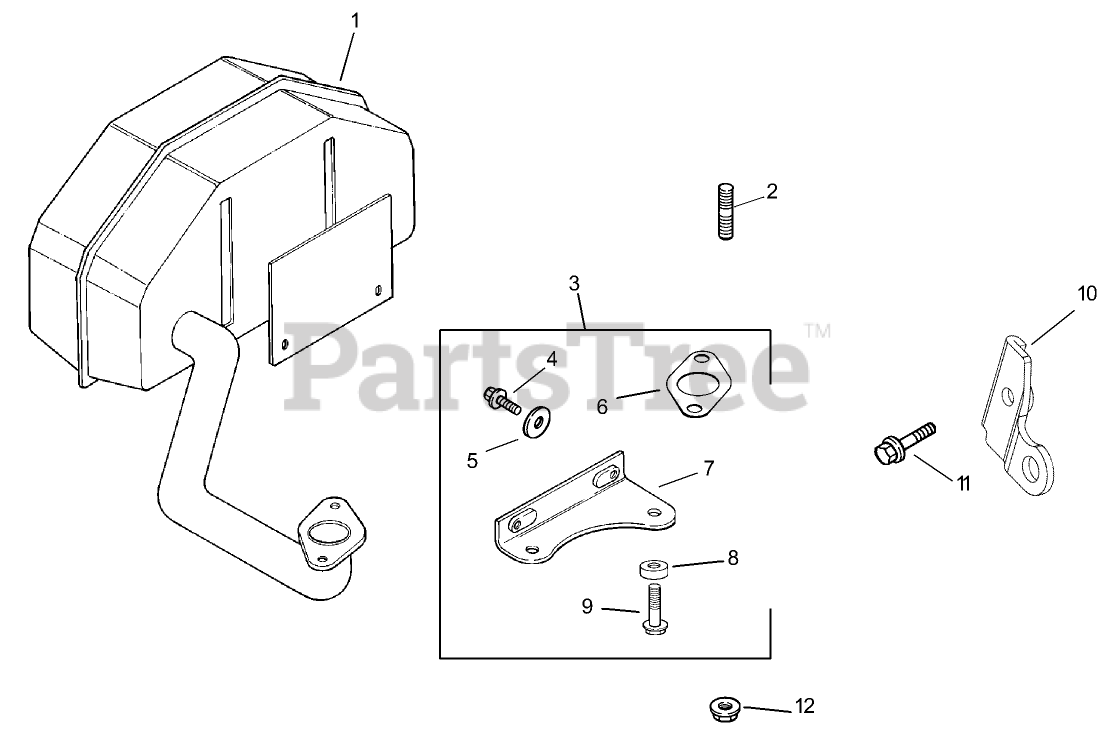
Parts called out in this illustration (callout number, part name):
1	Muffler
2	STUD (M8X1.25X33)
3	Kit, bracket (Incl. Ref. #4-9)
4	Screw-HF (M6x1.0x12)
5	Washer-Flat (1/4)
6	Gasket-Manifold, Exhaust
7	Bracket-Muffler
8	Washer
9	Screw-HF (M8x1.25x 50)
10	Bracket-Strap, Lifting
11	SCREW-HHFTF (M6X1.0X20)
12	NUT-FLANGE (M8X1.25)
